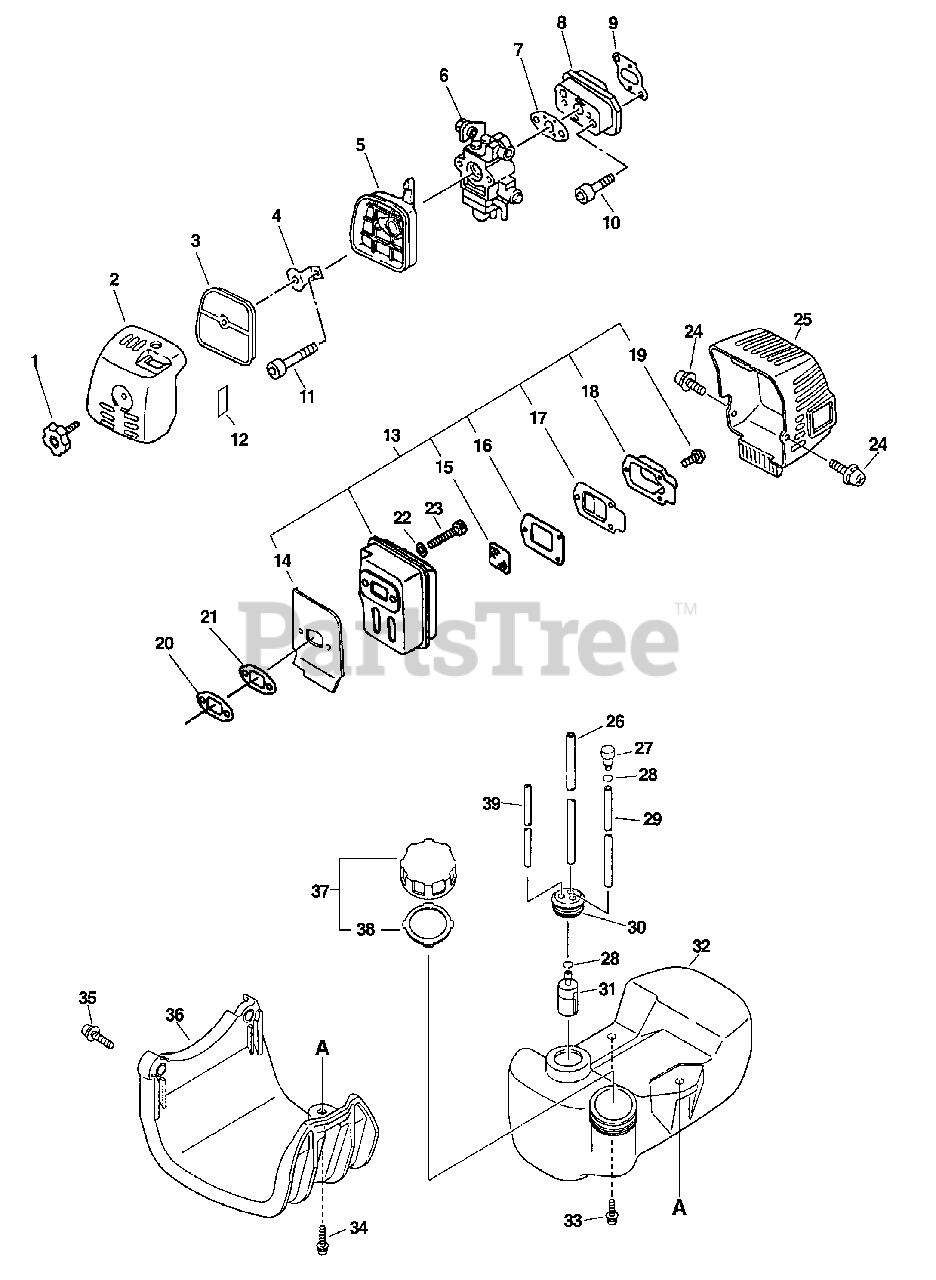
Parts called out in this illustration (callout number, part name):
1	THUMBSCREW
2	COVER, AIR FILTER
3	FILTER, HEAVY-DUTY AIR
4	PLATE, PREVENT
5	CASE, AIR FILTER
6	CARBURETOR - WYJ-192
7	GASKET, CARBURETOR
8	INSULATOR, INTAKE
9	GASKET, INTAKE
10	BOLT 5×25
11	SCREW 5×55
12	LABEL - CHOKE
13	MUFFLER ASSY
14	GASKET, EXHAUST
15	SCREEN, SPARK ARRESTER
16	GASKET, EXHAUST
17	GUIDE, EXHAUST
18	OUTLET, EXHAUST
19	SCREW 4×10
20	GASKET, EXHAUST
21	SPACER
22	WASHER, FLAT 5.5×10×0.8
23	BOLT 5×55
24	BOLT 5×12
25	COVER, MUFFLER
26	PIPE, FUEL 3×6×170
27	VENT ASSY
28	CLIP Ø6.5 MM
29	PIPE, FUEL 3×6×100
30	GROMMET, FUEL
31	FILTER, FUEL
32	TANK, FUEL
33	SCREW 5×16
34	SCREW 5×20
35	BOLT 5×22
36	GUARD, FUEL TANK
37	CAP ASSY, FUEL
38	GASKET, FUEL CAP
39	PIPE, FUEL 3×6×60 CLEAR
